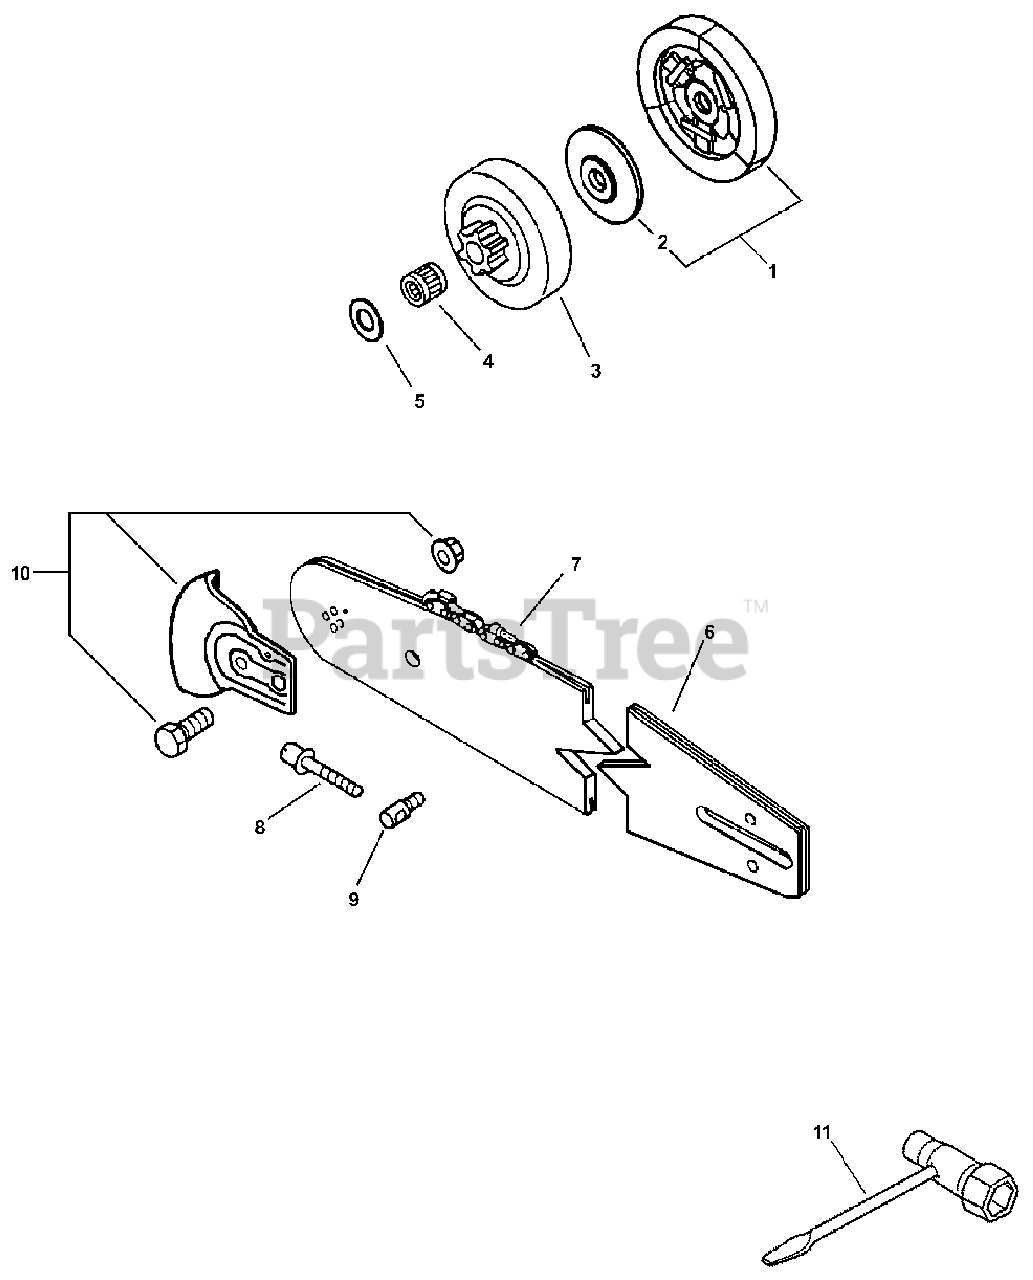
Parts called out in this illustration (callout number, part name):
1	CLUTCH ASSY
2	PLATE, CLUTCH
3	DRUM, CLUTCH 3/8"
4	BEARING, NEEDLE 10×13×10
5	WASHER 10.2×24.5×1.2
6	GUIDE BAR, 12" DOUBLE-GUARD
6	GUIDE BAR, 14" DOUBLE-GUARD
6	GUIDE BAR, 16" DOUBLE-GUARD
7	SAWING CHAIN - 12" -- XTRAGUARD
7	SAW CHAIN 14" XTRAGUARD
7	SAW CHAIN 16"
9	TENSIONER, CHAIN
10	KICK GUARD KIT
11	T-WRENCH 10×19 MM
